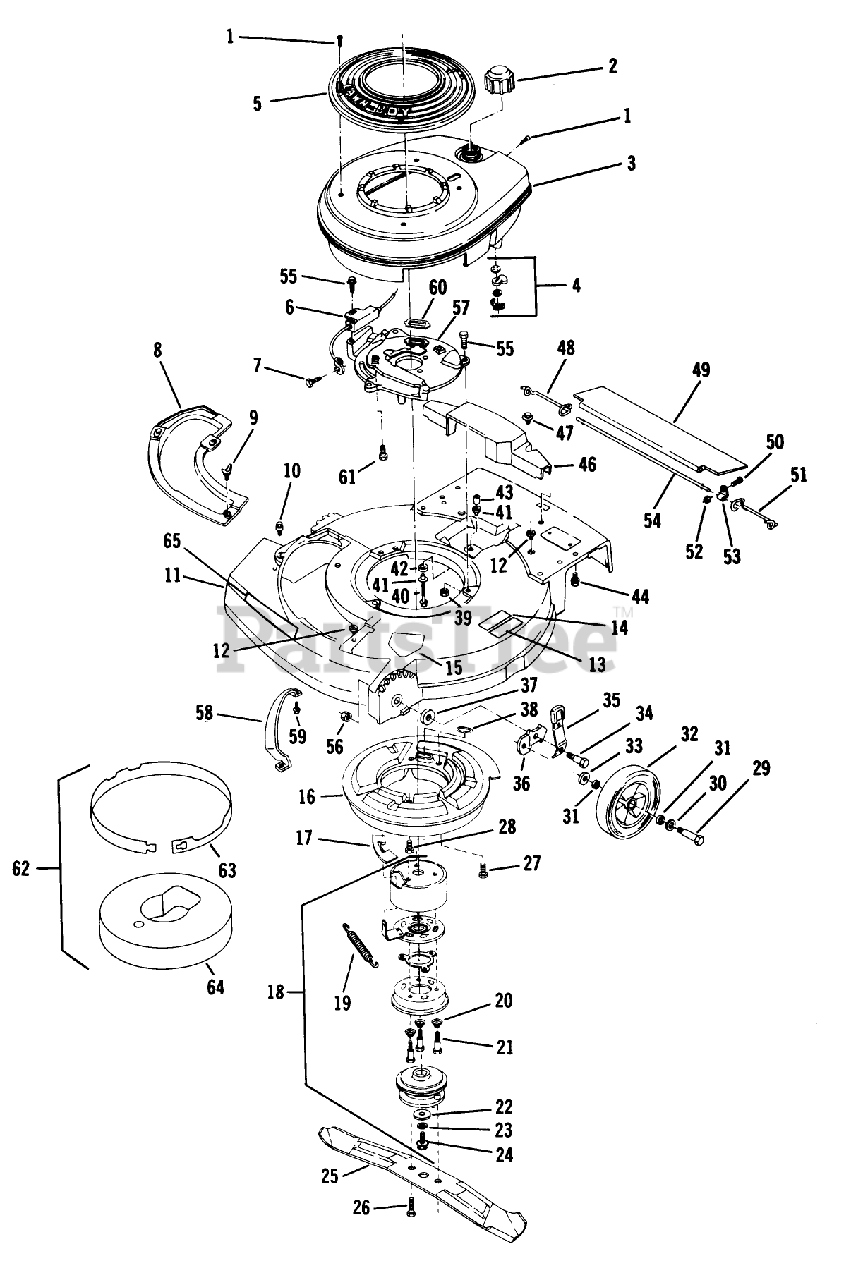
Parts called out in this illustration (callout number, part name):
1	SCREW - SELF TAPPING
2	FUEL CAP & INSERT
4	SHUT OFF VALVE KIT
6	CONTROL CABLE
9	WING SCREW LAWRE
13	PAD FOOT
19	SPRING
21	SCREW,SHOULDER SM
22	WASHER
26	SCREW SEMS
28	SCREW
29	BOLT WHEEL
30	SPACER
31	WASHER
32	WHEEL & TIRE KIT
33	WASHER WROUGHT
34	BOLT
37	WASHER
38	SEAL
39	NUT-LOCK F
41	SPACER ECK PRES
42	GROMMET
43	SPACER
44	SCREW
48	SPRING;TRAILING SHIELD RH
49	SHIELD
51	SPRIG T/SHLD ASOC
52	LOCKNUT E
53	CLAMP ROD KMC
54	ROD 21" ADVANCE
55	SCREW-HH
56	LOCKNUT
58	BAR-TOE
61	SCREW V
